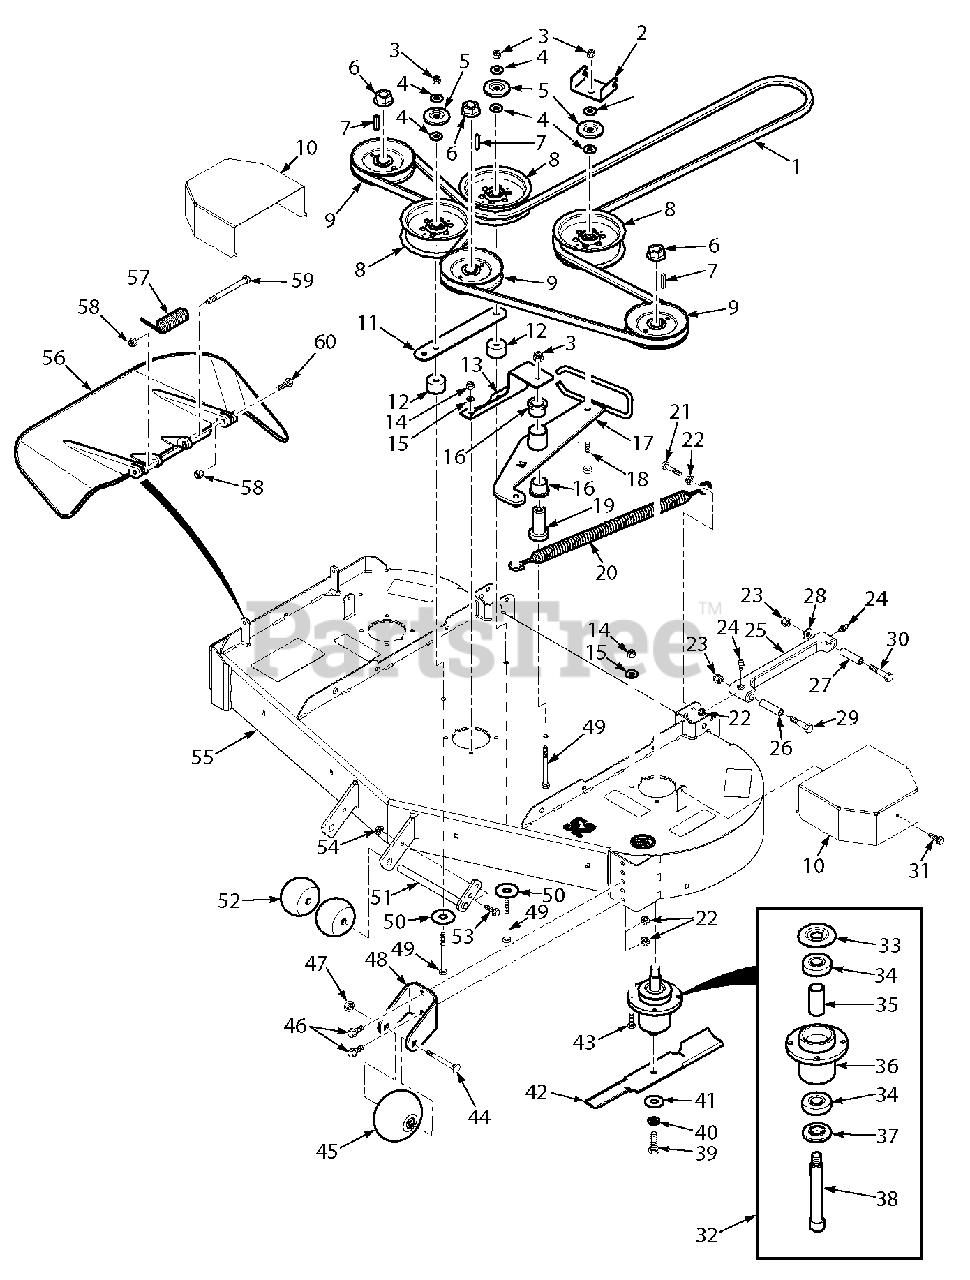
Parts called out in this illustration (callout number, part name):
1	Belt, Cutter Deck -48
1	Belt, Cutter Deck - 52
2	Bracket, Belt Guide
3	Nut, 3/8-16 x 16 Elastic Stop
4	Flatwasher, 3/8-.391 x .938 x .105
5	Dust Shield
6	Nut, 3/4-16 Spiral Lock
7	Key, 1/4 x 1/4 x 1-1/4"
8	Pulley, 5" Idler
9	Pulley, 5.13" OD - 25mm Bore
9	Pulley, 5.73" OD - 25mm Bore
10	Belt Cover, SZL
11	Brace, Pulley
12	Spacer
13	Support, Idler Pivot - 48
13	Support, Idler Pivot - 52
14	Nut, 5/16-18 Elastic Stop Grade 8
15	Lockwasher, 5/16"
16	Bearing, 1" ID
17	Idler Arm Assembly
18	Bolt, Hex Head 3/8-16 x 2-1/2"
19	Pivot, Idler
20	Spring, Cutter Deck Idler
21	Bolt, Hex Head 3/8-16 x 1-1/2" Gr.8
22	Nut, 3/8-16 Serrated Flange
23	Nut, 1/2-13 Elastic Stop
24	Grease Fitting, 1/4-28 Self Tap
25	Pusharm Assembly, LH
25	Pusharm Assembly, RH
26	Spacer, Pusharm - Deck
27	Spacer, Pusharm - Axle
28	Flatwasher, 1/2-.531 x 1.062 x .095
29	Bolt, Hex Head 1/2-13 x 3-1/2"
30	Bolt, Hex Head 1/2-13 x 2-1/2"
31	Screw, 1/4-20 x .375"
32	Spindle Assembly
33	Debris Shield
34	Bearing
35	Spacer
36	Spindle Housing
37	Protector, Bearing
38	Shaft, Spindle
39	Bolt, Hex Head 5/8-11 x 1-1/2"
40	Lockwasher, 5/8"
41	Flatwasher, 5/8-.688 x 1.75 x .134 HD
42	Cutter Blade, 16-1/2"
42	Cutter Blade, 18"
43	Bolt, Hex Head 5/16-18 x 1-1/2" Gr.8
44	Bolt, Carriage 3/8-16 x 4"
45	Wheel, Anti-Scalp
46	Bolt, Hex Head Serr. Flange 3/8-16 x 1"
47	Nut, 3/8-16 Center Lock
48	Bracket, Anti-Scalp
49	Bolt, Hex Head 3/8-16 x 3-1/2"
50	Flatwasher, 3/8-.406 x 2.250 x .188
51	Shaft Weldment, Guide Roller
52	Wheel, Anti-Scalp
53	Bolt, Hex Head 5/16-18 x 1"
54	Nut, 5/16-18 Flange Elastic Stop
55	Cutter Deck w/Decals
56	Discharge Chute
57	Spring, Discharge Chute
58	Nut, 5/16-18 Elastic Stop
59	Bolt, Hex Head 5/16-18 x 4-3/4"
60	Bolt, Hex Head 5/16-18 x 1-3/4"
